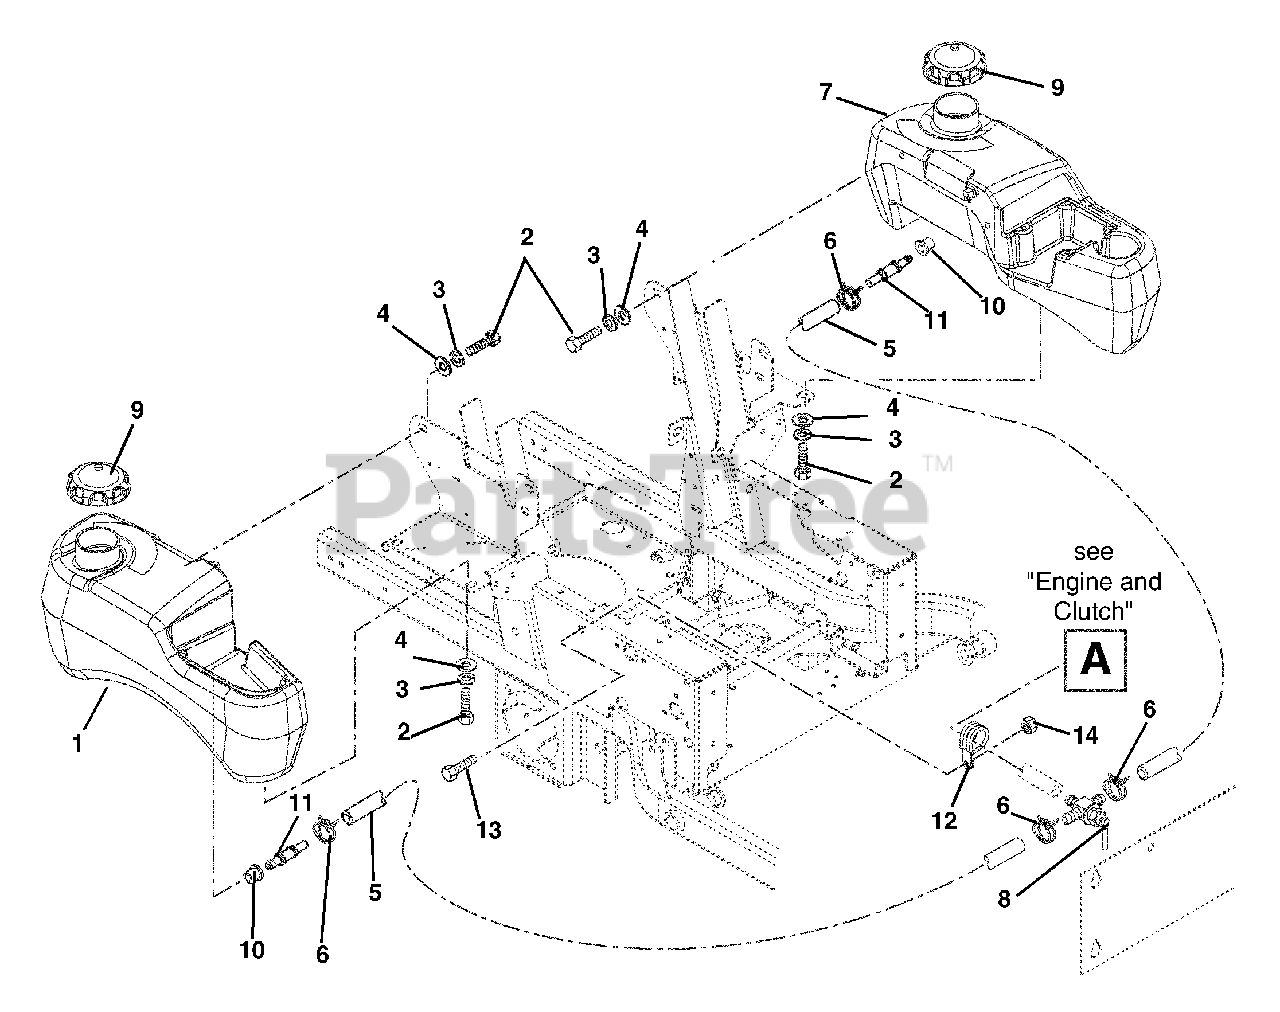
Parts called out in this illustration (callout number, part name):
1	TANK, GAS - RH W/O HOSE
2	@BLT-HEX .31-18X.75 GR5 YWZC
3	@WSHR-LK .31X.078 REG YWZC
4	@WSHR-FL-STL.38X.875X.083 YWZC
5	GAS LINE-BULK 1/4" I.D.
6	CLAMP-HOSE WIRE .490/.510X.116
7	TANK, LH FUEL 100 S. W/O HOSE
8	VALVE, FUEL
9	CAP - FUEL
10	BSHG-FLG .375 X 1.062 X .625 R
11	FITTING, TANK
12	CLAMP, CUSHIONED STEEL
13	@BLT-HEX .38-16X1.00 GR5 YWZC
14	@NUT-LK-TOP-FLG .38-16 YWZC
